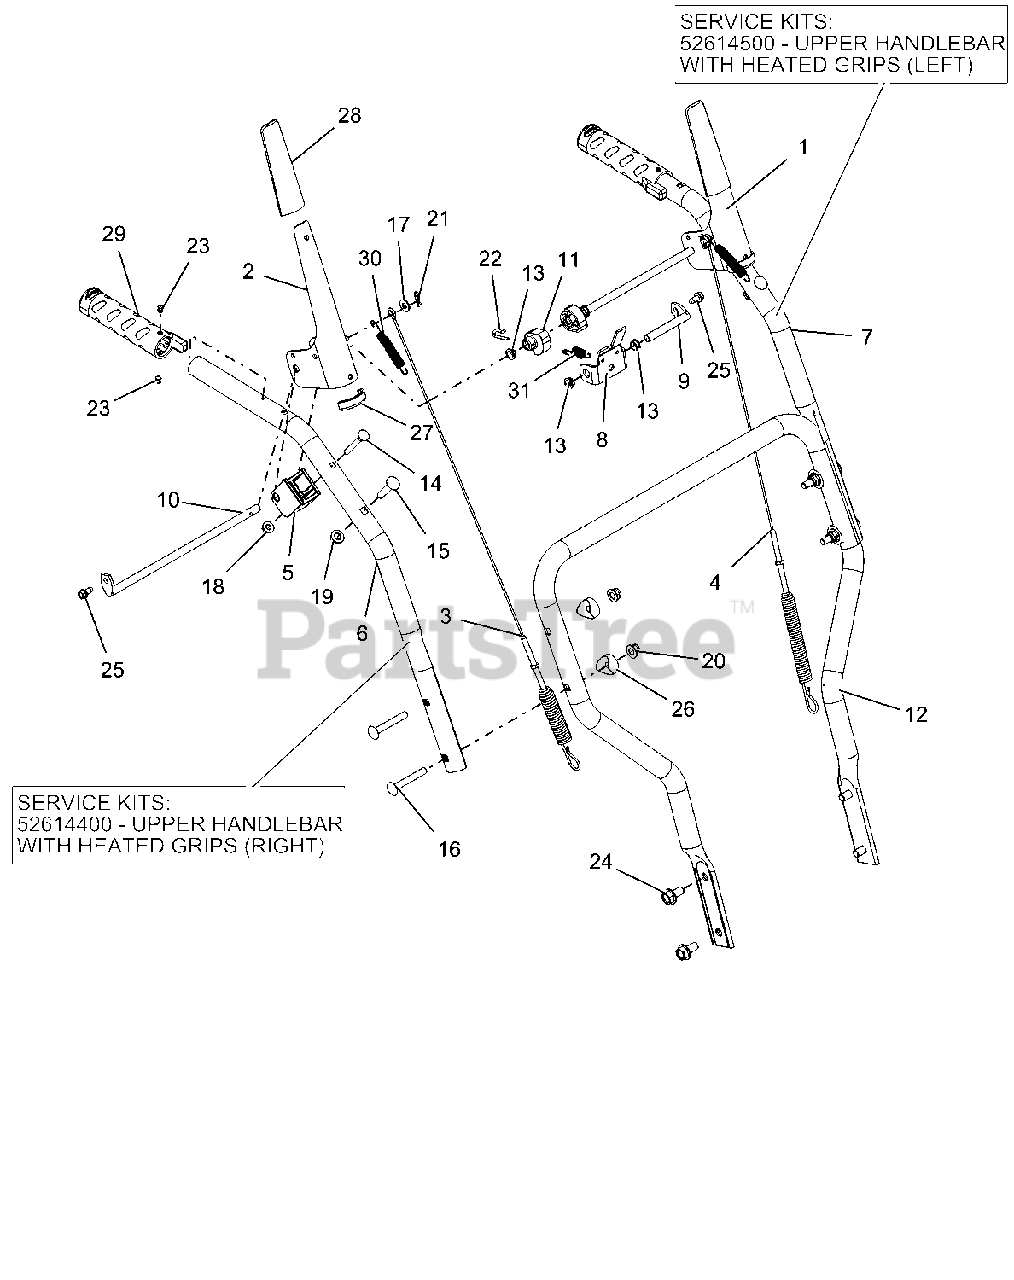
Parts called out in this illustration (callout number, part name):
1	LEVER, CLUTCH-LH
2	LEVER, CLUTCH-RH
3	CABLE, AUGER (DELUXE & PRO)
4	CABLE, UPPER TRACTION
5	BLOCK, CLUTCH PADDLE
6	HANDLEBAR, UPPER - RH
6	KIT, HANDLEBAR HW RH
7	HANDLEBAR, UPPER - LH
7	KIT, HANDLEBAR HW LH
8	BRACKET, INTERLOCK ARM
9	ROD, PIVOT - INTERLOCK
10	ROD, PADDLE MOUNT - PRO
11	CAM, INTERLOCK
12	HANDLEBAR, LOWER - DELUXE
13	BUSHING, POLYLINER-.38 SNAPIN
14	BLT-RDHDXLSQNK .25-20X2.0 G5YZ
15	@BLT-RDHDSQNK .31-18X1.50 G5YZ
16	@BLT-RDHDSQNK .31-18X2.25 G5YZ
17	@WSHR-FL-STL.281X.62X.065 YWZC
18	@NUT-LK-CTR-FLG .25-20 YWZC
19	@NUT-LK-TOP-FLG .31-18 YWZC
20	@NUT-LK-NYL-FLG .31-18 YWZC
21	PIN-HAIR INT .06X.18X.77
22	PIN, SPRING CLIP
23	RVT-POP #43 .125X.313 STL ZINC
24	BLT-SERHFWH .38-16X.75 YWZC
25	SCR-TAP .25-20X.50 HWH TR YWZ
26	SPACER, HANDLEBAR
27	EDGING, CLUTCH PADDLE - 2.00"
28	SLEEVE, CLUTCH PADDLE-GRAY
29	GRIP,HEATED HANDLE-GRAY
30	SPRING, EXTENSION
31	SPRING-EXT .047X.438X1.45
